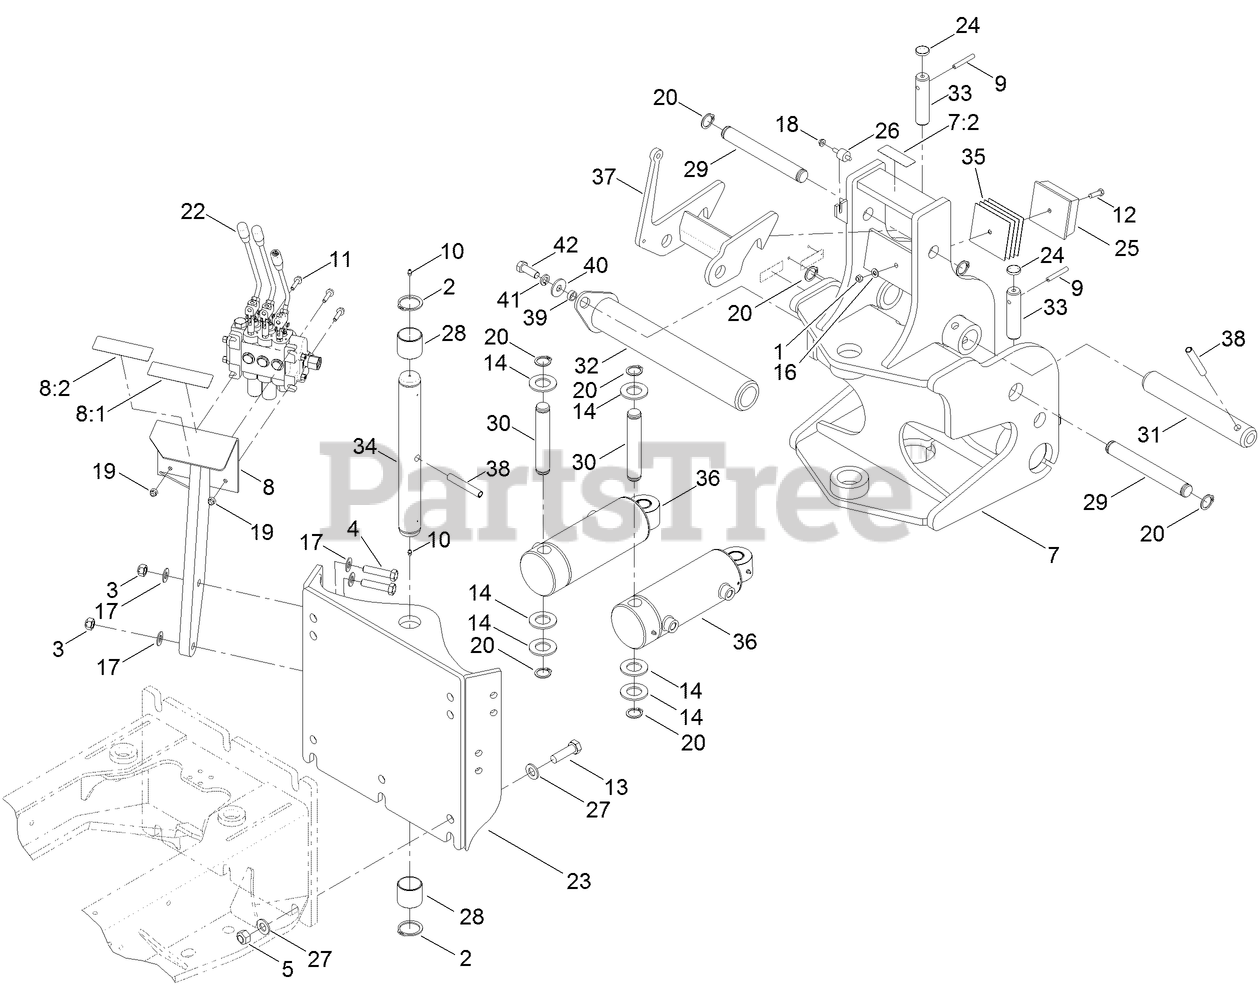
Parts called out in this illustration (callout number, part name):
1	NUT-HEX
2	RING-RETAINING, EXTERNAL
3	NUT-CROWNLOCK
4	SCREW-HH
5	NUT-LOCK
7	FRAME-SWING W/DECAL
7:2	DECAL-DANGER
8	PEDESTAL-PLOW VALVE W/DECAL
8:1	DECAL-PLOW CONTROL
8:2	DECAL-PLOW FLOAT
9	PIN-ROLL
10	FITTING-GREASE
11	SCREW-HHF
12	SCREW-HH
14	WASHER-FLAT
16	WASHER-FLAT
17	WASHER-FLAT
18	NUT-HF
19	NUT-LOCK, HHF
20	RING-RETAINING, EXTERNAL
22	VALVE-3-BANK CONTROL, PLOW
23	MOUNT-PLOW
24	PLUG-FREEZE
25	BUMPER
26	MOUNT-RADIATOR
27	WASHER-Flat
28	BEARING-PIVOT
29	PIN-PLOW
31	PIN-PLOW ARM, UPPER
32	PIN-FLAGGED
33	PIN-ROD
34	PIN-plow swing
35	SHIM-BUMPER
36	HYD CYLINDER ASM
37	LATCH-TRANSPORT
38	PIN-SPIRAL
39	SPACER-PIN FLAG
40	WASHER-FLAT
41	WASHER-LOCK/SP
42	SCREW-HH
